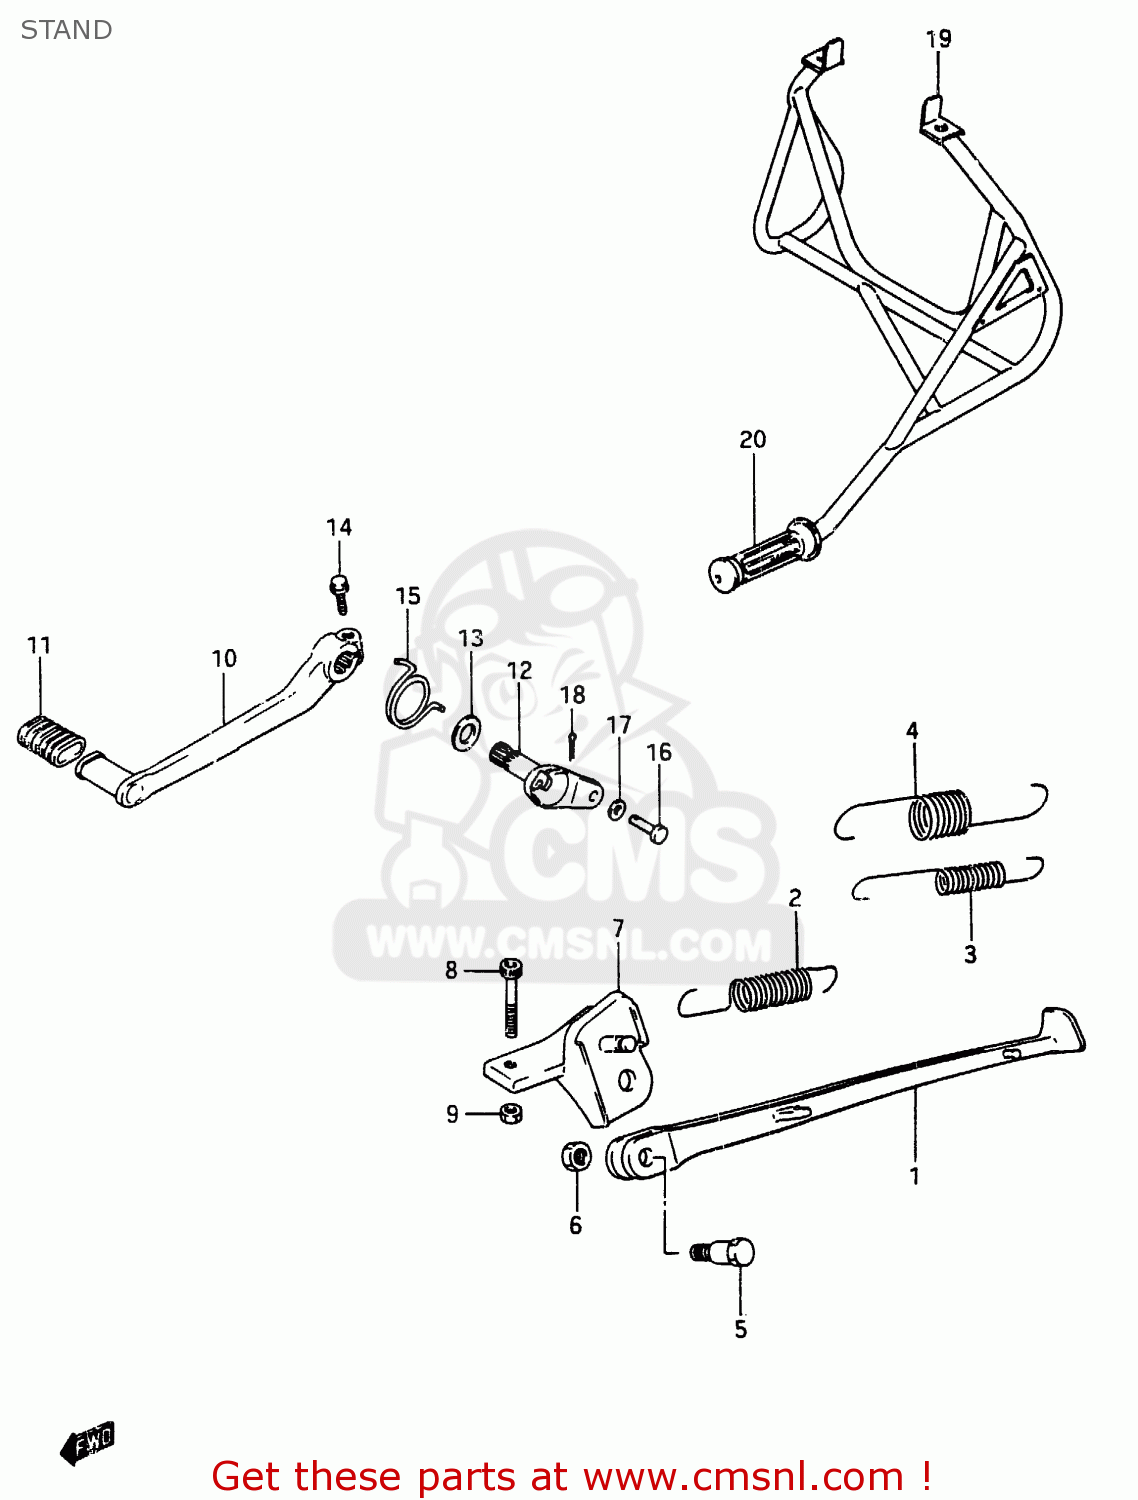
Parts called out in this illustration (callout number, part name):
1	STAND, PROP
2	SPRING
3	SPRING
4	SPRING
5	BOLT L:30
6	NUT
7	BRACKET, PROP STAND
8	BOLT
9	NUT 8MM
10	PEDAL, BRAKE
11	RUBBER,BRAKE PEDAL
12	ARM, BRAKE ROD
13	WASHER,BRAKE PEDAL
14	BOLT
15	SPRING
16	PIN
17	WASHER
18	PIN
19	STAND ASSY, REAR
20	GRIP,L
